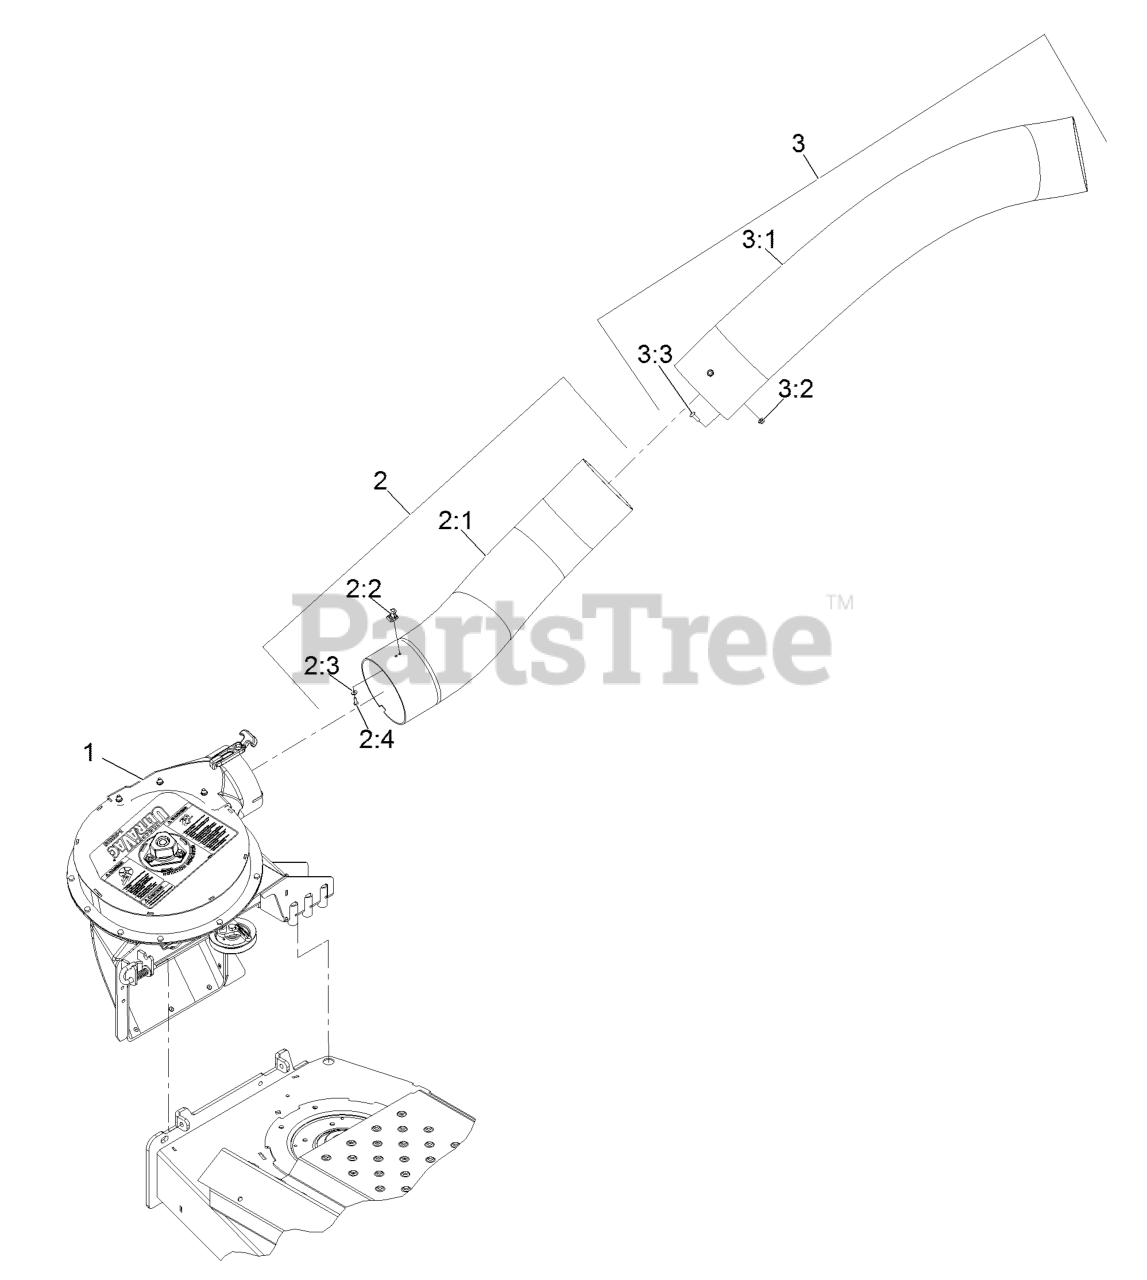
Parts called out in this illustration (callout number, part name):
1	ASM-BLOWER UV E SERVICE
2	LOWER TUBE ASM
2:1	TUBE-LOWER
2:2	LATCH-KEEPER
2:3	WASHER-FLAT
2:4	SCREW-PPH
3	UPPER TUBE ASM
3:1	TUBE-UPPER
